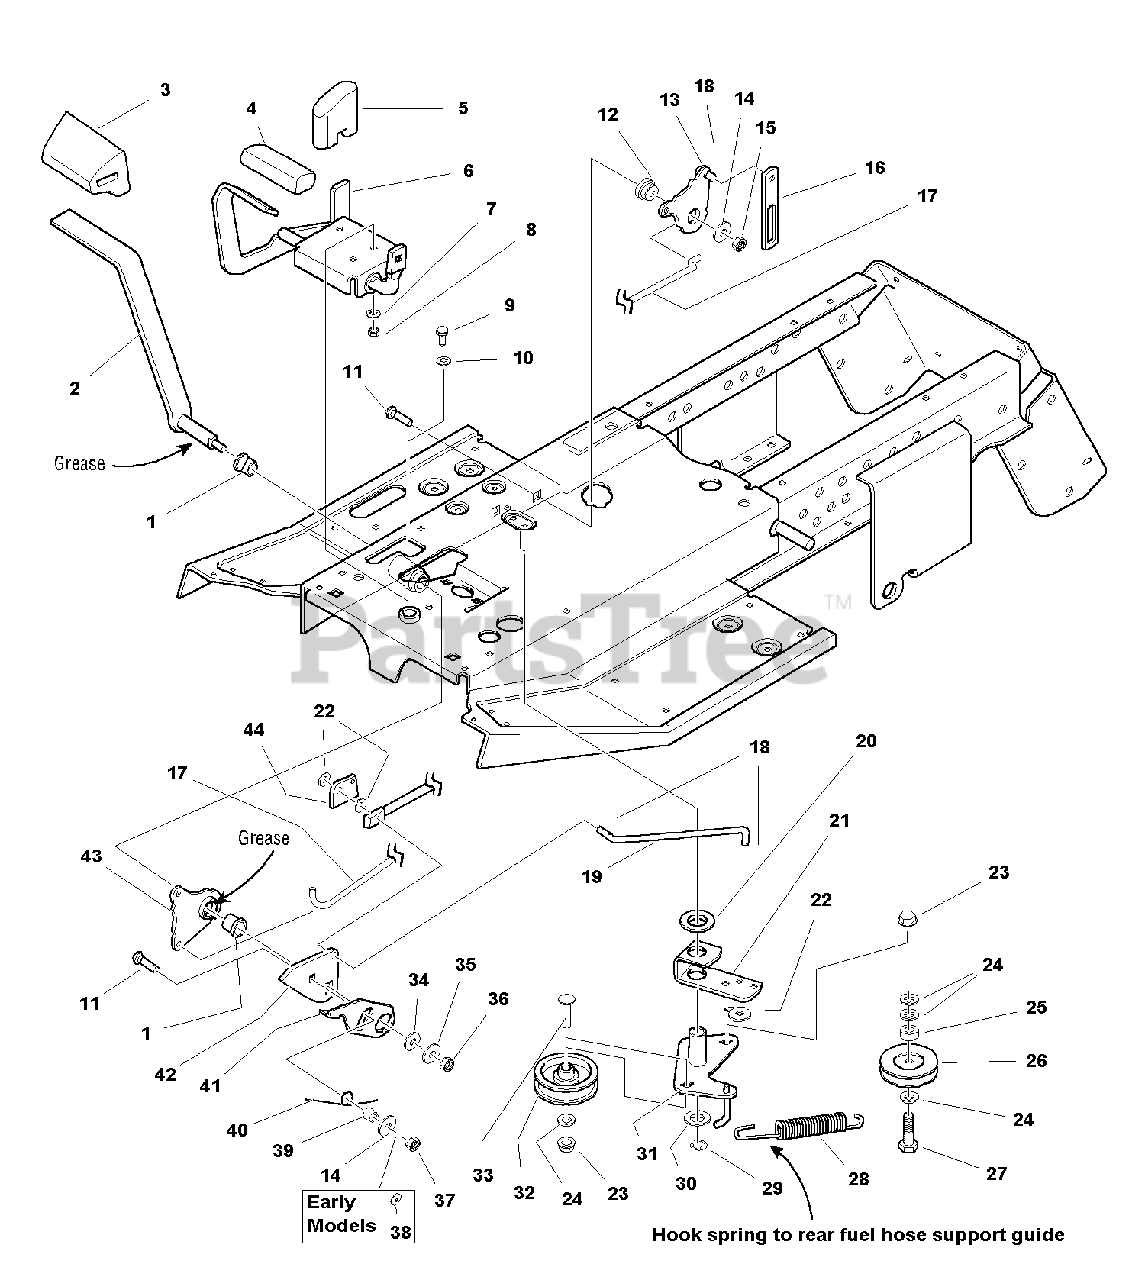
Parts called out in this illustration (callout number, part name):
1	BUSHING, Nylon
2	PEDAL & SHAFT ASSEMBLY, Brake
3	PAD, Foot Pedal, Black Rubber
4	PEDAL, Foot Forward, Balck Rubber
5	PEDAL, Foot Reverse, Black Rubber
6	PEDAL ASSEMBLY, Foot
7	LOCKWASHER, 3/8
8	NUT, Hex, 3/8-16
9	CAPSCREW, Hex Head, 3/8-16 x 1
10	LOCKWASHER, External Tooth, 3/8
11	CARRIAGE BOLT, 5/16-18 x 1-1/4
12	SPACER
13	CAM & WELD PIN ASSEMBLY, Lift
14	WASHER, 5/16
15	NUT, Hex Lock ESNA Light, 5/16-18
16	LINK, LIFT, Upper
18	PIN, Cotter, 3/32 X 3/4
19	ROD, Clutch 2 Bends
21	LEVER, Clutch Painted
22	WASHER, 5/16
23	NUT, Hex Flange Whizlock, 3/8-16
24	WASHER, 3/8
27	CAPSCREW, 3/8-16 x 1-3/4
28	SPRING, Extension
29	RING, Extension Klipring
30	WASHER, 5/8
31	PIVOT ASSEMBLY, Idler
32	PULLEY, Idler
33	CARRIAGE BOLT, 3/8-16 x 1-3/4
34	WASHER, 3/8
35	WASHER, 3/8
36	NUT, Hex Lock ESNA Light, 3/8-16
37	NUT, Hex Center Lock, 5/16-18
38	LOCKWASHER, 5/16 (Early Models)
40	SPRING, Torsion
41	ACTUATOR, Switch
42	ARM, Foot Pedal
43	CAM, Lift Painted
44	CAM, Parking Brake
